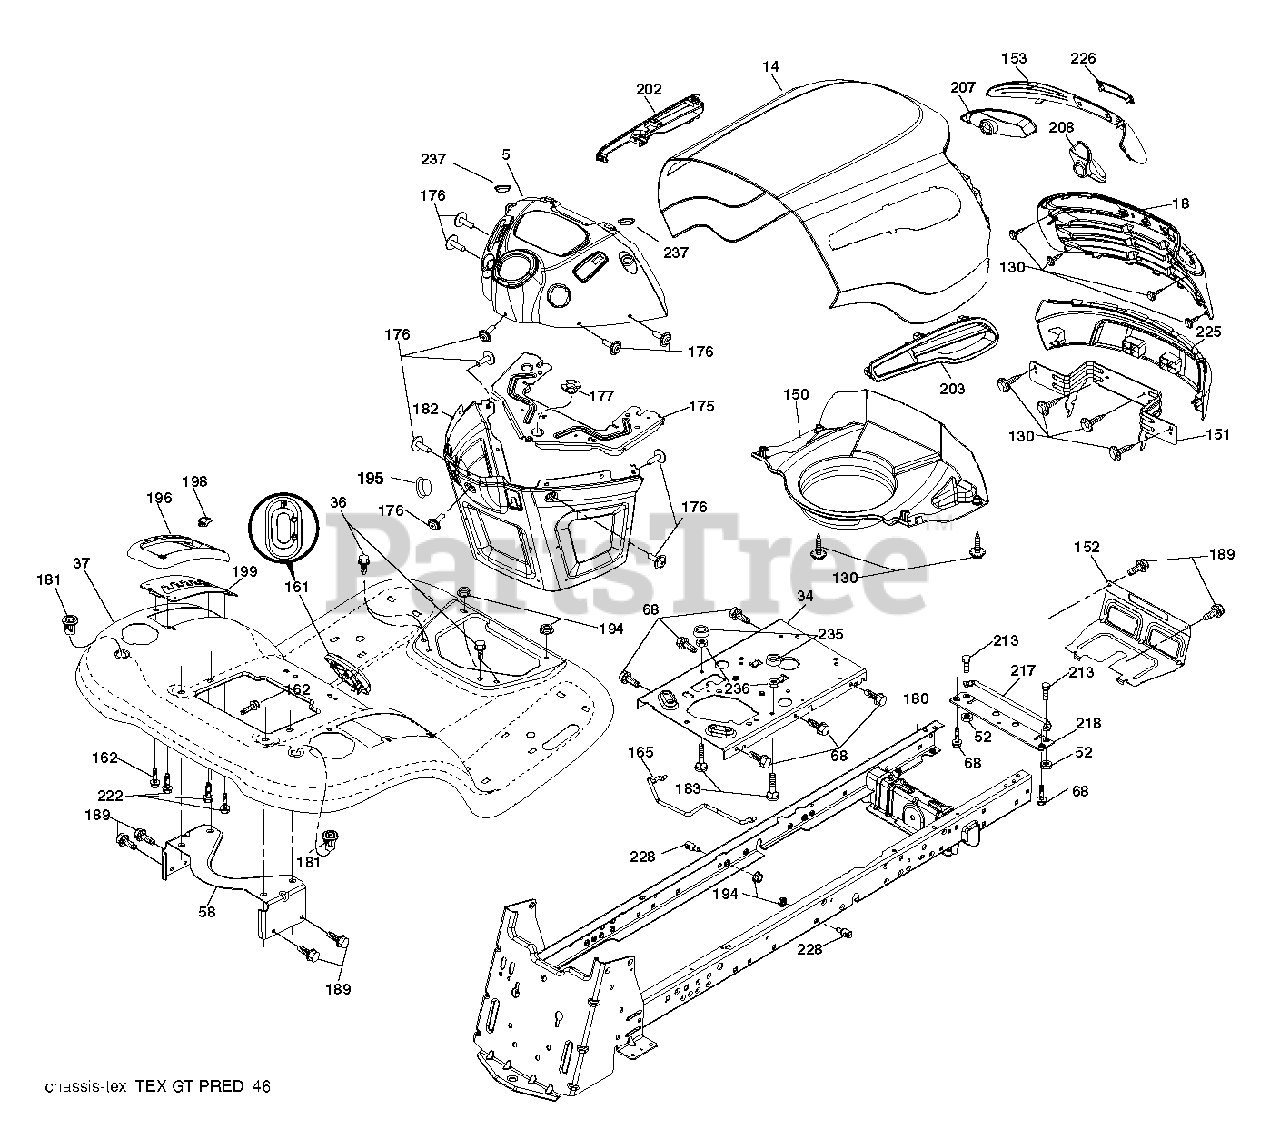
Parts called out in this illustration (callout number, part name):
34	PLATE.ENGINE.WELDED.CHASSIS
36	SCREW 5/16"
52	LOCKNUT
58	BRKT.SUPPORT.FNDR/TANK
68	SCREW LT
130	SCREW.#10 X 0.750.BOS THREAD
152	SHIELD BROWNING
161	CONSOLE.FUEL.WINDOW.STGT.BLACK
162	SCREW.HI-LO.CONSOLE
165	SUPPORT.TANK.REAR.W/TE
175	PLATE.CROSSMEMBER.HUSQ
176	SCREW.#10-24X5/8.RN.QU
177	BUSHING,STEERING
180	CHASSIS.GT.SLOPED.DRAWBAR.
181	FEND/FTRST.PCH.CPH.NFW
182	DASH.LOWER.COMMON.12V.ADAPTOR
183	BOLT.5/16-18X1-1/4 FULL.THREAD
189	SCREW
194	NUT LOCK HEX FLANGE 5/16-18
195	PLUG.HOLE.DASH.LOWER.12V.BLK
198	INDICATOR.DECK.LIFT.RED
199	PLATE DECK LIFT
213	BOLT
217	ROD.PIVOT.HOOD
218	X-PIECE.HOOD.STOP.NON/
222	SCREW.1/4-20X5/8
228	STUD.FASTNER.W/ANTI-ROTATE
235	SPACER FENDER
236	NUT.CENTERLOCK.5/16-
237	PLUG.MOUNT.CARGO.BLK
